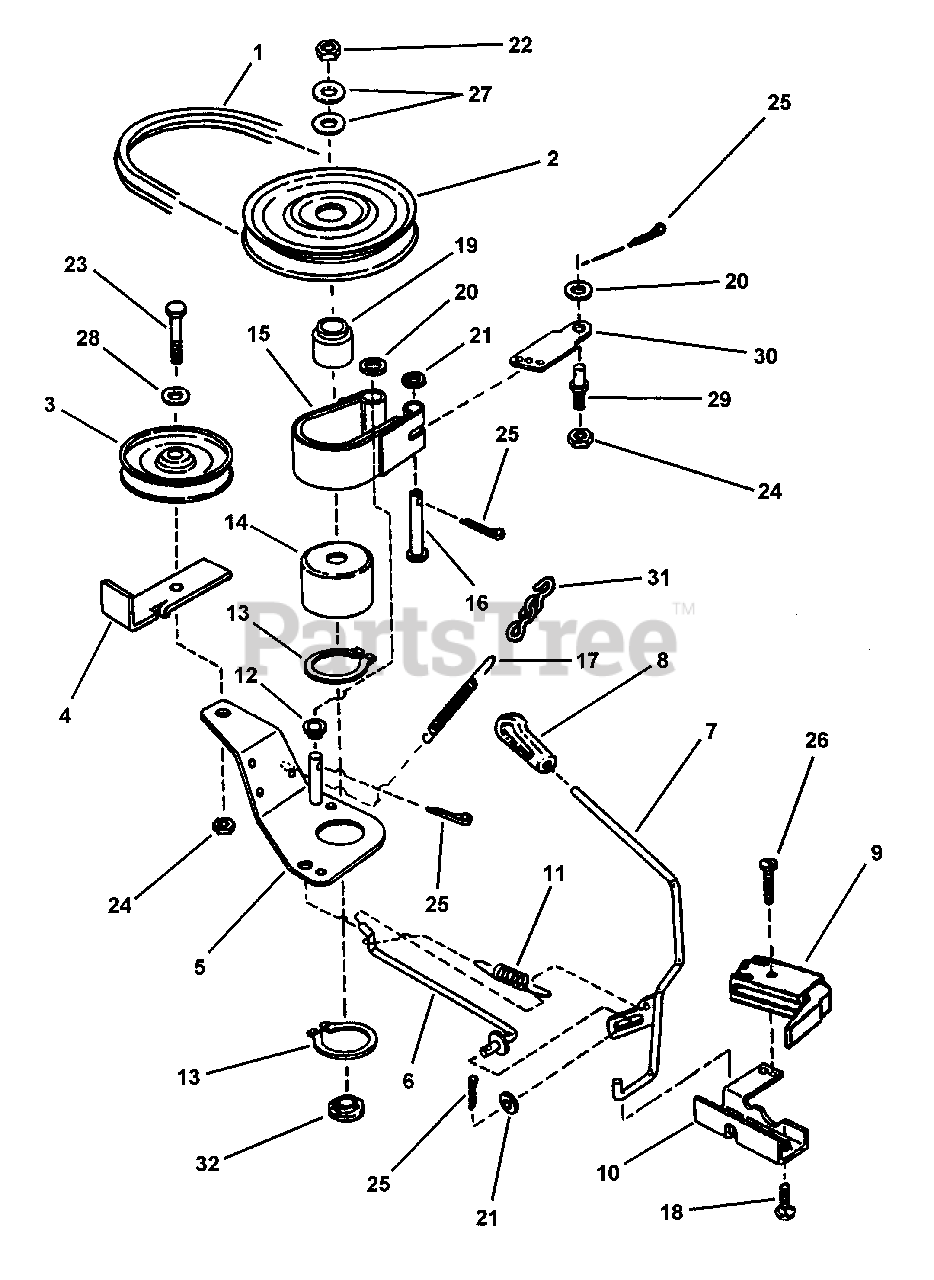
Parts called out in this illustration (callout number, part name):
1	BELT, Drive
2	PULLEY, Spindle
3	PULLEY, Idler
4	RESTRICTOR, Belt
5	WELDMENT, Idler Arm
6	ROD, Idler
7	HANDLE, Blade Lever (On-Off)
8	GRIP, Handle
9	SWITCH, Deck Interlock
10	MOUNT, Blade Lever and Switch
11	SPRING, Blade Handle
12	SPACER
13	RING, 2" External Retaining
14	DRUM, Brake
15	BAND, Brake
16	PIN, 1/4 x 1-5/8" Clevis
17	SPRING
18	SCREW, 1/4-20 x 5/8" Self-Tap
19	HUB, Pulley
20	WASHER, 3/8" Flat
21	WASHER, 1/4" Flat
22	NUT, 3/4-16 Hex Jam
23	SCREW, 3/8-16 x 1-1/2" Hex Cap, Grade 5
24	NUT, 3/8-16 Hex Nyloc
25	PIN, 3/32 x 3/4" Cotter
26	SCREW, #10-32 x 1" Hex Washer Self-Tap
27	WASHER, 49/64 x 1-1/2" Flat
28	WASHER, 3/8" Flat
29	STUD (3/8-24 Thread)
30	BRACKET, Brake Anchor
31	LINK, Chain
32	WASHER, Spindle
